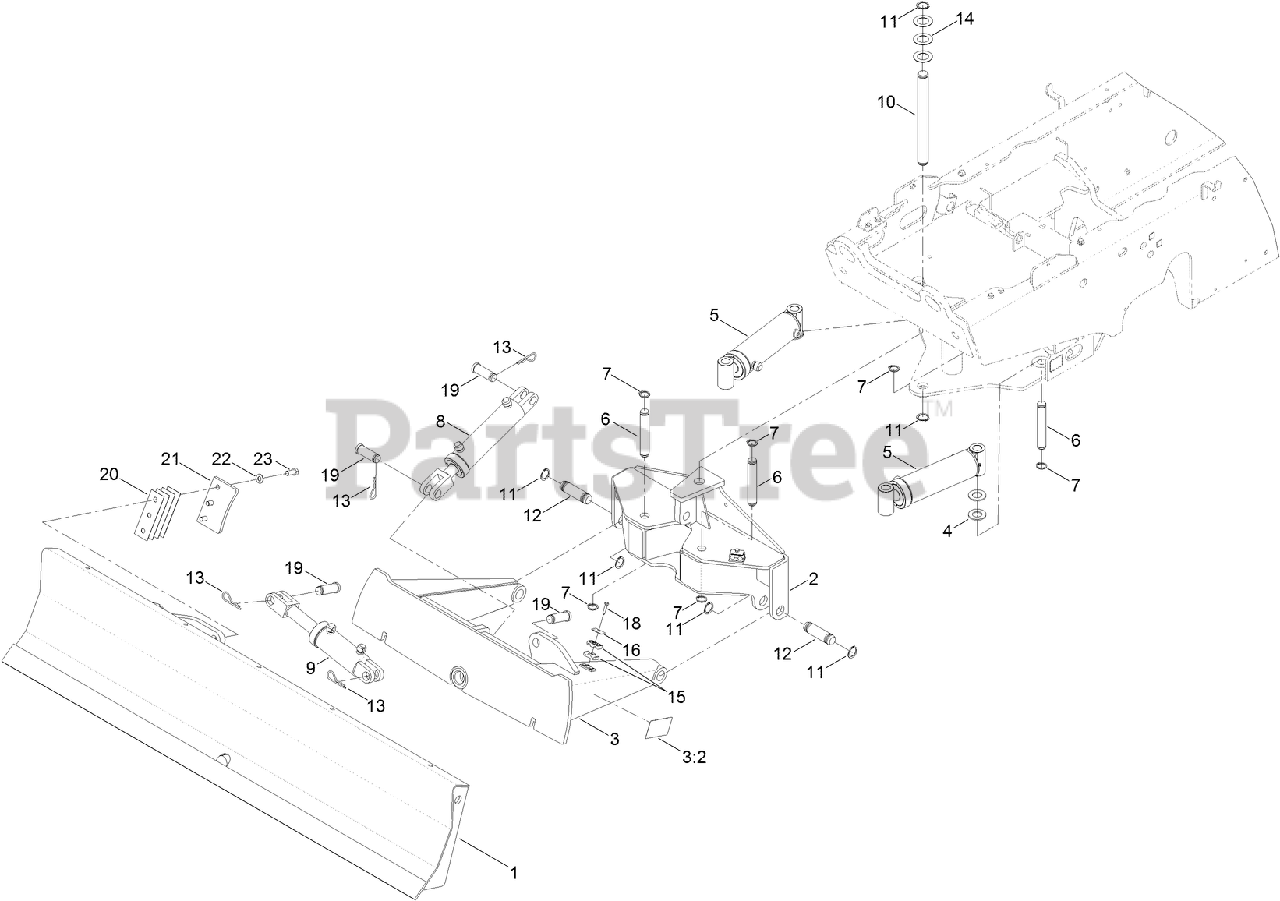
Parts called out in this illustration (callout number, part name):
1	BLADE-BACKFILL
2	PIVOT-BLADE, BACKFILL
3	BACKFILL ARM ASM
3:2	DECAL-DANGER
4	WASHER-FLAT
5	HYD CYLINDER ASM
6	PIN-ANGLE, CYLINDER
7	RING-RETAINING, EXTERNAL
8	HYD CYLINDER ASM
9	HYD CYLINDER ASM
10	PIN-BLADE
12	PIN-BLADE
13	PIN-COTTER, QUICK ATTACH
15	CLAMP-TUBE
16	COVERPLATE
18	SCREW-HH
19	PIN-CLEVIS
20	SHIM-RETAINER
21	RETAINER-BLADE
22	WASHER-FLAT
23	SCREW-HH
